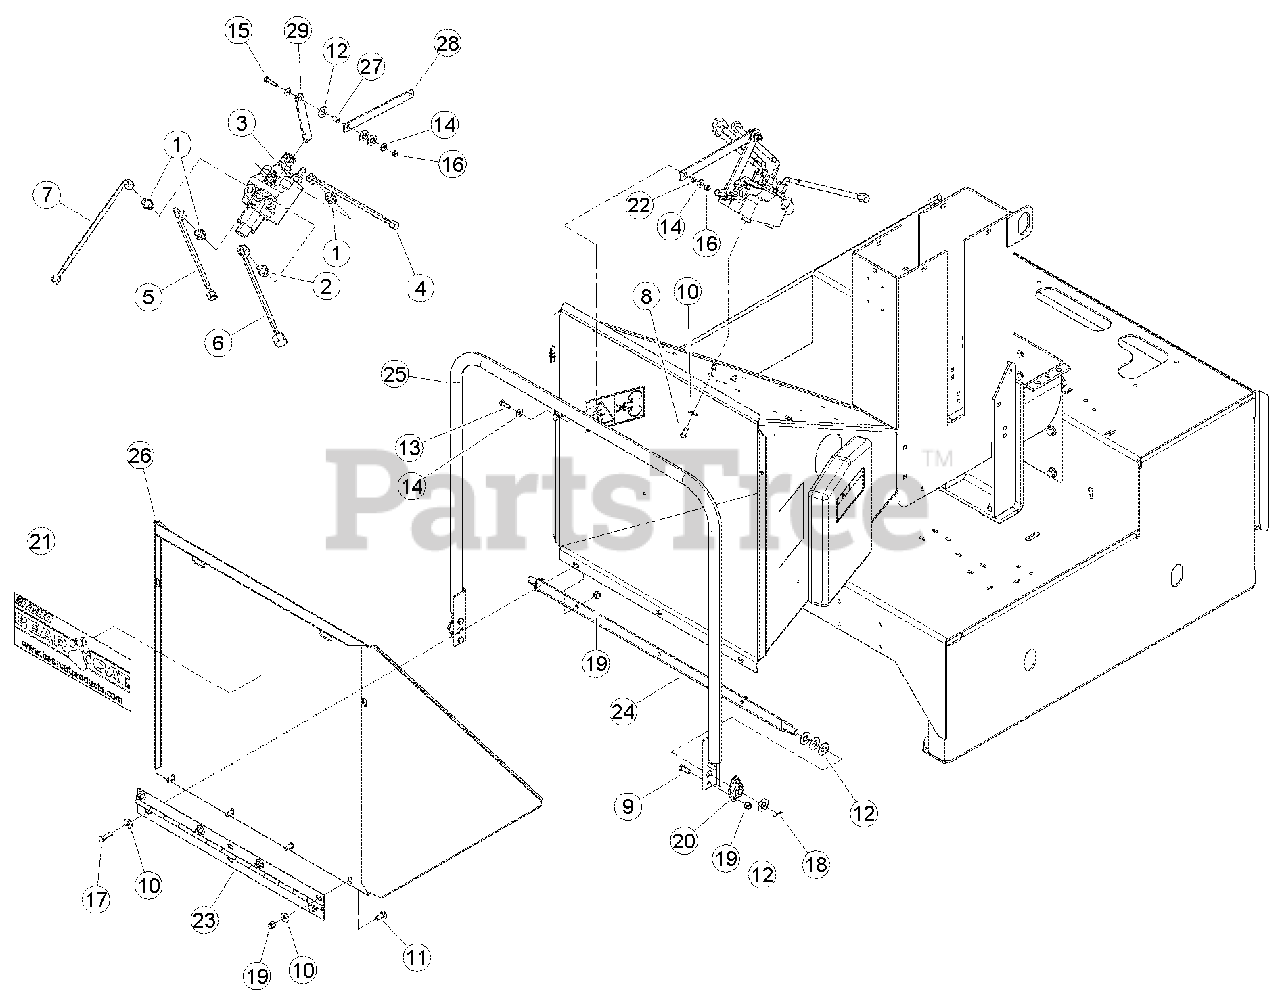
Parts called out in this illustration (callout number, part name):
1	ADAPTER, -8 MORING / -8 MJIC
2	ADAPTER, -10 MORING / -8 MJIC
3	VALVE, 4 POSITION W/DETENTS
4	HOSE ASSY, -8 FMJIC / -8 FMJICSW 90 DEG. X 37
5	HOSE ASSY, -8 FMJIC / -8 FMJICSW 90 DEG. X 35
6	HOSE ASSY, -10 FMJIC / -8 FMJICSW 90 DEG. X 53
7	HOSE ASSY, -10 FMJIC / -8 FMJICSW 90 DEG. X 82
8	BOLT, 3/8 X 3/4 HEX HD GR5 ZP
9	BOLT, 3/8 X 1 HEX HD GR5 ZP
10	WASHER, 3/8 FLAT ZP
11	BOLT, 3/8 X 1 CRG GR5 NC ZP
12	WASHER, 5/8 SAE FLAT ZP
13	BOLT, 5/16 X 1 HEX HD GR5 NC ZP
14	WASHER, 5/16 FLAT ZP
15	BOLT, 5/16 X 1-1/2 HEX HD GR5 ZP
16	NUT, 5/16 NE NYLOCK ZP
17	BOLT, 3/8 X 1-1/4 HEX HD GR5 ZP
18	PIN, 1/8 X 1.00 COTTER ZP
19	NUT, 3/8 NE NYLOCK ZP
20	BEARING, SIDE FLANGE MOUNT, 5/8"
21	DECAL, BEARCAT WEB
22	SPACER, IDLER PIVOT
23	HINGE, EXTENSION TRAY
24	WELDMENT, CONTROL PIVOT
25	WELDMENT, CONTROL ARM
26	WELDMENT, CHUTE EXTENTION TRAY
27	SPACER, .50 X .775
28	LEVER, VALVE CONTROL
29	LINK, VALVE CONTROL
